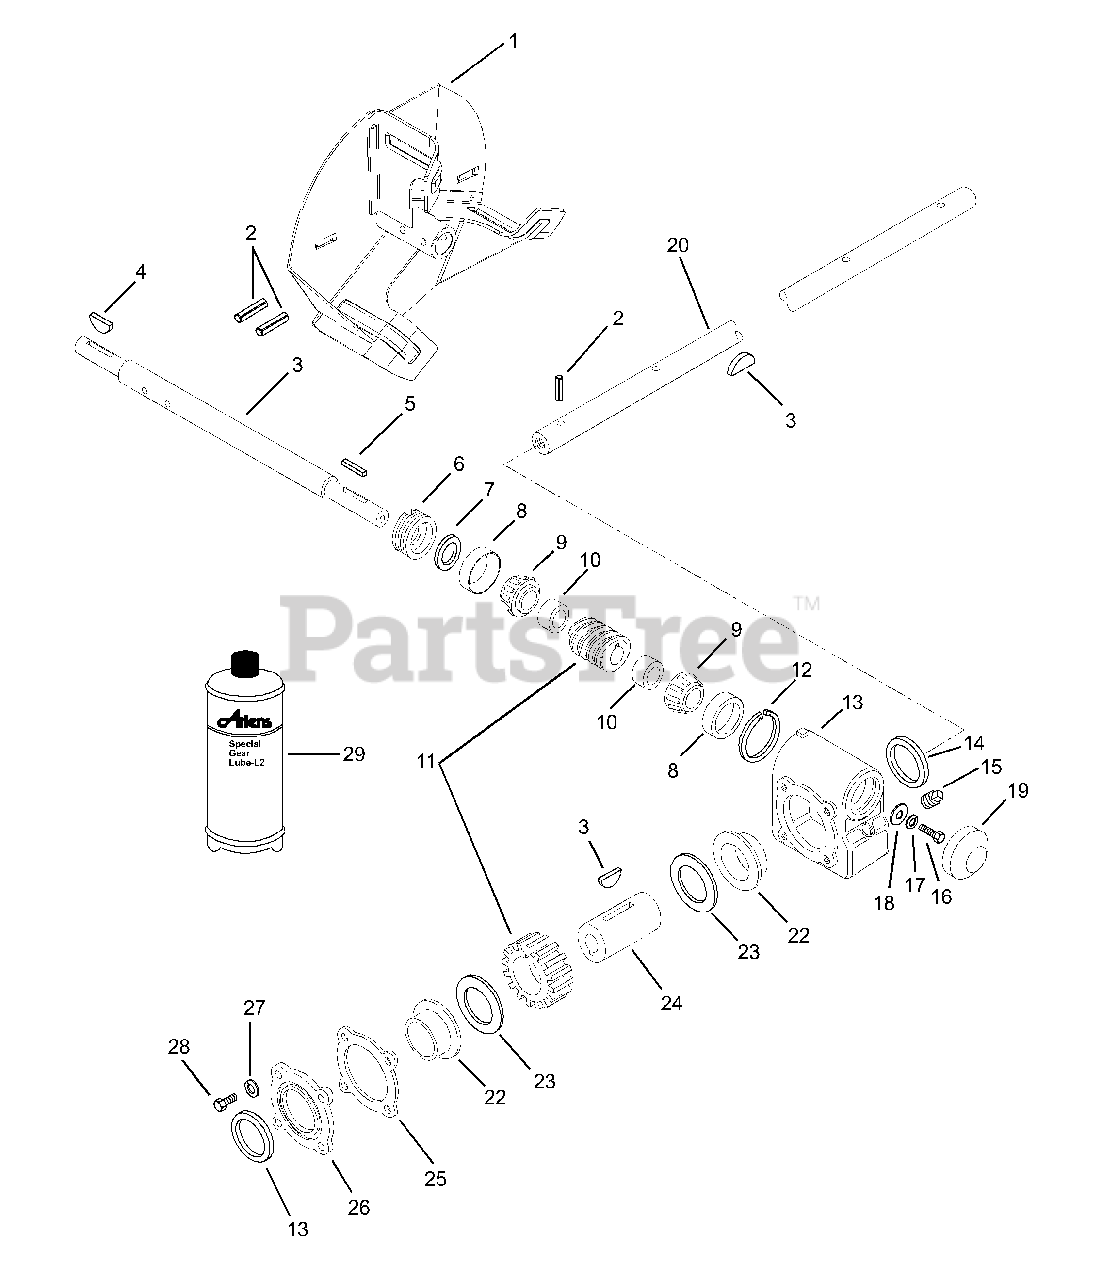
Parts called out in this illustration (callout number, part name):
1	Fan
2	Pin-Roll .313 x 1.75
3	Worm Shaft
4	Key-Woodruff .25 x .875 x .375
5	Key-Square .188 x 1.0 x .188
6	Adjustment Plug
7	Seal 1.000 x 1.312 x .150
8	Bearing-Cup 1.781 x .475
9	Bearing-Cone .750 x .61
10	Bearing Spacer 1.12 x 1.52 x .5
11	Worm & Gear Service Assembly
12	Ring-Retaining-Internal 1.781 x .062
13	Gear Case
14	Seal 1.625 x 2.125 x .250
15	Pipe Plug
16	Bolt-Hex .31-18 x .75 Grade 5
17	Washer-Lock .312 x .078
18	Washer-Flat-Steel .38 x .875 x .083
19	Dust Cap
20	Rake Shaft
21	Pin-Roll .188 x 1.50
22	Bushing-Flange 1.625 x 1.87 x 1.68 x 2.25
23	Washer-Flat-Steel 1.625 x 2.500 x .012
24	Gear Case Shaft
25	Gasket
26	Gear Case Cover
27	Washer-Lock External .262 x .502 x .026
28	Bolt-Hex .25-20 x .75 Grade 5
29	Ariens 16 Oz. Bottles of L2 Lube
